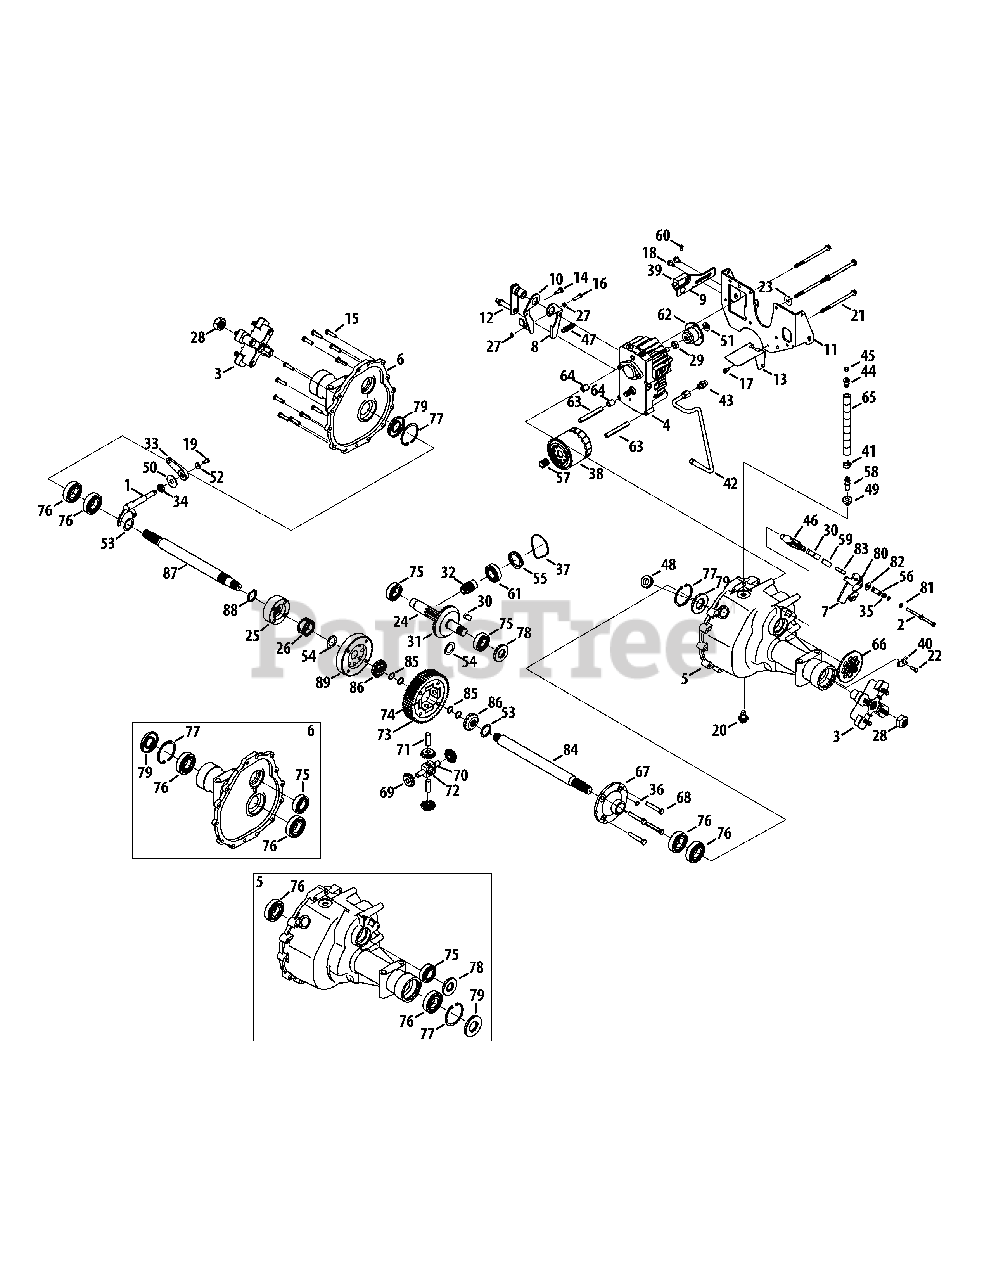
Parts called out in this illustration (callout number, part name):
1	Actuator Shift Assembly
2	Hex Washer Screw, 1/4-20 x 2.25
3	Wheel Hub Assembly
4	Pump Assembly
5	RH Housing
6	LH Housing
7	Brake Arm Actuator
8	Neutral Arm, LH
9	Neutral Return Arm
10	Neutral Arm
11	Torque Bracket
12	Neutral Control Arm
13	Hydro Dump Spring Plate
14	Hex Screw, 5/16-24 x .625
15	Hex Lock Screw, 5/16-18 x 1.25
16	Hex Screw, 1/4-20 x 1.00
17	Hex Washer Screw, 1/4-20 x .500
18	Hex Washer Screw, 5/16-18 x .500
19	Hex Cap Screw, 1/4-20 x .620
20	Plug Screw, M14 x 1.5 x .827
21	Hex Washer Screw, 5/16-18 x 5.350
22	Hex Screw, 1/4-20 x .75
23	Flat Washer, .345 x 1.00 x .07
24	Output Shaft, 9T
25	Differential Collar Assembly
26	Spring, Compression
27	Jam Nut, 1/4-20
28	Nut, Lock, 7/8-14
29	Jam Lock Nut, 1/2-20
30	Brake Pad
31	Bevel Gear, 54T
32	Bevel Gear, 13T
33	Actuator Arm
35	Hex Lock Nut, 5/16-24
36	0-Ring, .426 x .566 x .070
37	Gland Seal
38	Oil Filter
39	Interlock Switch
40	Tube Clamp, .500
41	Fuel Clamp
42	Hydro Pick-Up Tube
43	Straight Fitting
44	Plastic Vent
45	Plastic Vent Cap
46	Brake Yoke
47	Extension Spring, .50 x 1.98
48	Rubber Grommet, .750 x 1.063 x .4375
49	Grommet, .362 x .56 x .63
50	Flat Washer, .51 x 1.5 x .07
51	Bell Washer, .525 x 1.00 x .050
52	Bell Washer, .265 x .750 x .060
53	Washer, Flat, 1.187 x 1.56 x .062
54	Thrust Washer, 1.007 x 1.542 x .03
55	Spring Washer, 1.595 x 2.011 x .030
56	Anti-Rotation Brake Bracket
57	Filter Nipple Fitting
58	Tube Fitting, .500
59	Puck Plate
60	Shoulder Screw, 10-32 x .500
61	Ball Bearing
62	Hydro Pump Adaopter
63	Hydro Spacer, .323 x .443 x 3.51
64	Hydro Spacer, .323 x .600 x .740
65	Fuel Line, 1/2
66	Disc Brake
67	Housing, Diff. Cover
68	Hex Cap Screw, 3/8-24 x 2.25 GR8
69	Gear, Differential 10T
70	Shaft, Cross, .5 x 3.485
71	Shaft, Cross, Special
72	Differential Pinion Block
73	Gear, Spur 60T
74	Block, Thrust Miter
75	Ball Bearing, 1 x 52 x 15
76	Ball Bearing
77	Retainer Ring
78	Oil Seal, 1.00 x 2.047 x .2755
79	Seal, Oil, 1.181 x 2.453 x .276
80	Torsion Spring, .75 x 3
81	Flat Washer, .281 x .50 x .063
82	Flat Washer, .343 x .880 x .062
83	Brake Actuator Pin
84	Axle Shaft, 1.181 x 15.08
85	Retaining Ring
86	Gear, 14T Differential Side
87	Axle Shaft, 1.181 x 15.08, LH
88	Retaining Ring
89	Housing, Diff Lock
